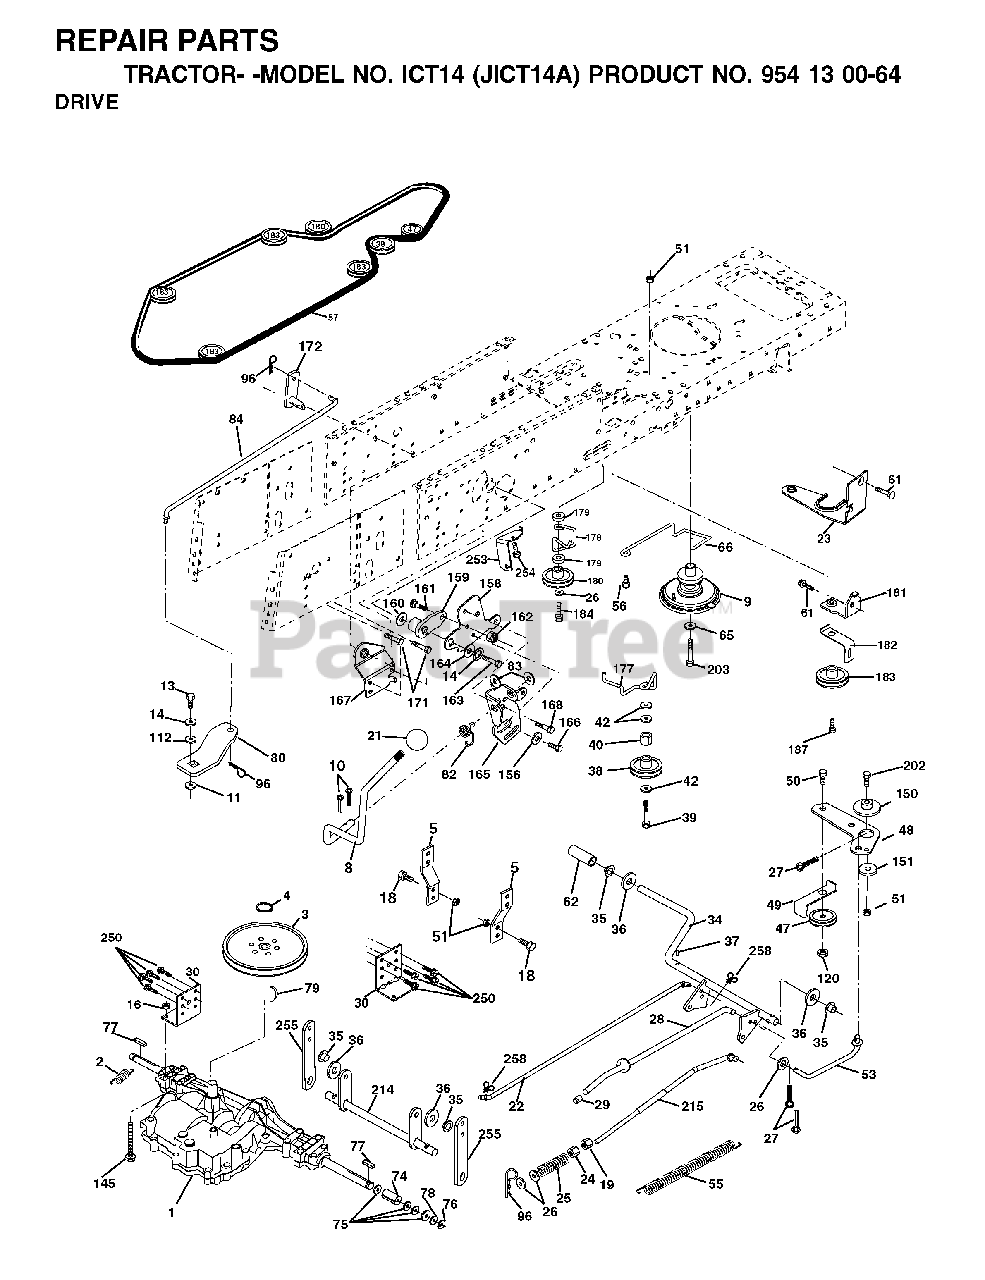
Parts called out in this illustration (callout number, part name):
2	SPRING,BRAKE RETURN
4	RETAINING RING LT
5	STRAP TORQUE
8	ROD SHIFT
9	CLUTCH ASSY
10	PIN COTTER
11	WASH-SHFT PLT LT
13	BOLT 1/4-28X3/4
14	LOCKWASHER
16	NUT.71038.31-18.HEX.NYLOCK
19	NUT
21	KNOB T (1/2-HOLE)
24	NUT
25	SPRING ROD LT
27	COTTER PIN
28	ROD, PARKING BRAKE
29	PLUNGER CAP
30	BRKT, MOUNT TRNSAXLE
34	SHAFT, FOOT PEDAL
35	BEARING.NYLON
36	WASHER LT
37	DRIVE PIN
38	PULLEY.FLAT
42	WASHER
47	IDLER PULLEY
48	BELLCRANK, CLUTCH
49	RETAIN BELT
50	BOLT
51	LOCKNUT
53	LINK, CLUTCH LT
55	SPRING, RETURN LT
56	SCREW.3/8-16
57	V-BELT.KEV.111"
61	SCREW 3/8-16X3/4
62	PEDAL COVER T
65	LOCKWASHER
66	KEEPER BELT ENGINE
74	SPACER AXLE
76	E-RING LT
77	SQUARE KEY
80	ARM SHIFT
82	SPRING,TORSION
83	WASHER
96	RETAINER M
112	WASHER LT
120	NUT LOCK FLG 3/8-16 UNC
150	BUSHING.BELLCRANK.GRD.DR
151	WASHER 12/32X2X10GA
156	WASHER.SRRTD.5/16
158	BRACKET
159	HUB
161	BOLT
162	NUT.CROWNLOCK.1/4
165	RP BRACKET
167	BRACKET
168	BOLT.SHOULDER.5/16-18X
180	PULLEY.FLAT.IDLER
182	KEEPER BELT
184	SCREW.HXWSH.3/8
187	BOLT.5/16-18X1.25
202	BOLT.3/8-16X1.50
250	SCREW 3/8-16X3/4
258	CLIP RETAINER
